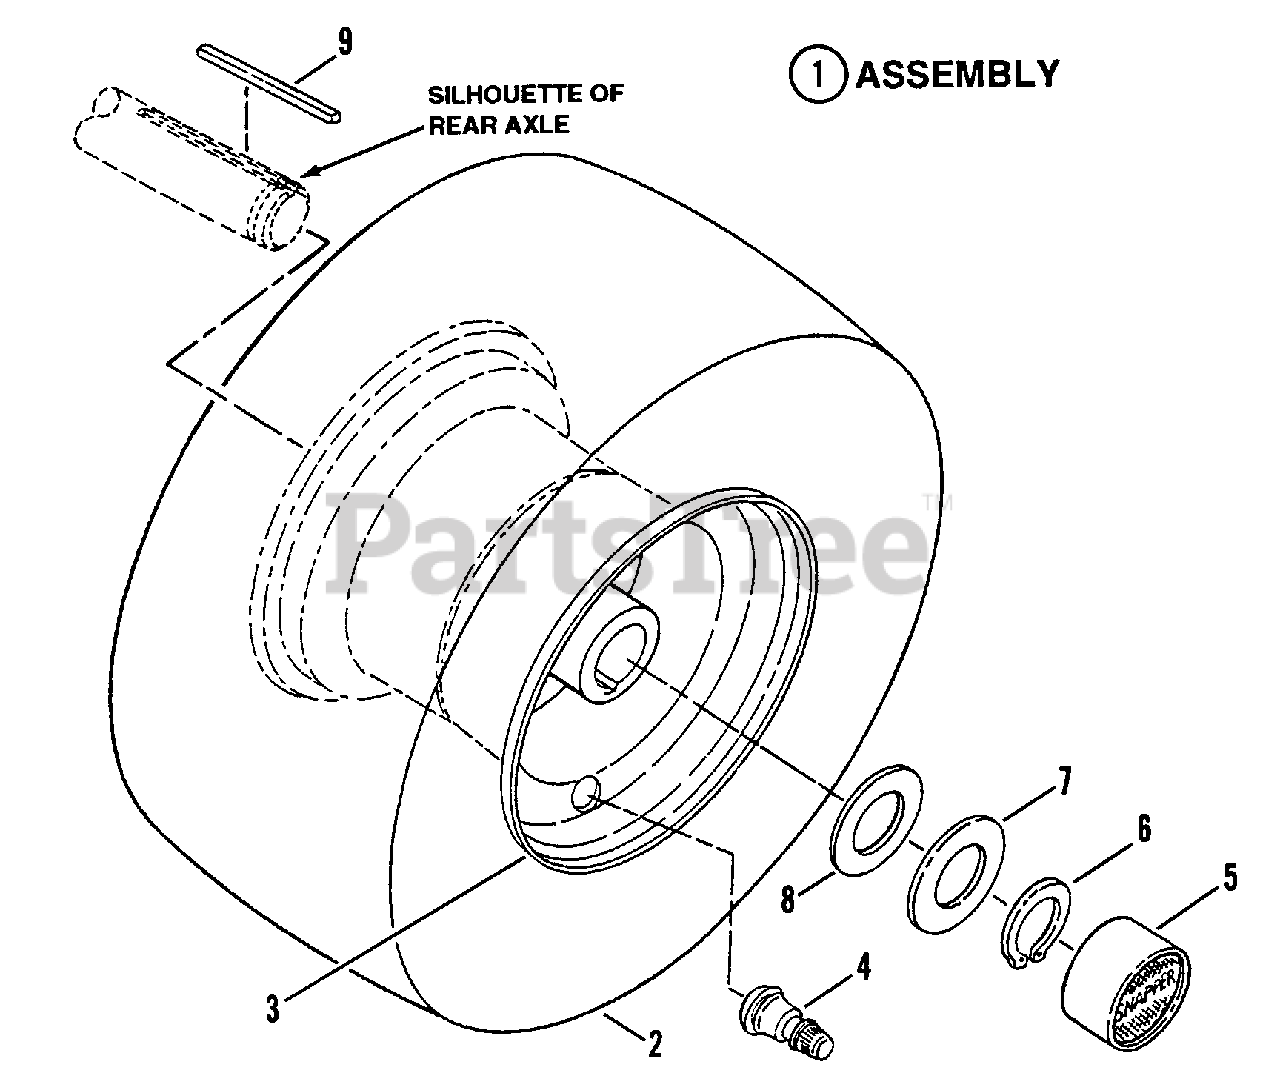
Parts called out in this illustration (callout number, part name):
1	ASSEMBLY, Rear Tire & Rim
2	TIRE, 18 x 7.50
2	TIRE, 18 x 8.50
3	RIM, 8.00 x 5.38
3	RIM, 8.00 x 7.00
4	VALVE, Air (Snap-in)
5	HUB-CAP
6	RING, Retaining
7	WASHER, 3/4 I.D. x1 5/8" O.D. Thrust
8	WASHER, 3/4 I.D. x 1 1/2" O.D. Flat
9	KEY, 3/16 x 2 1/2" Square
